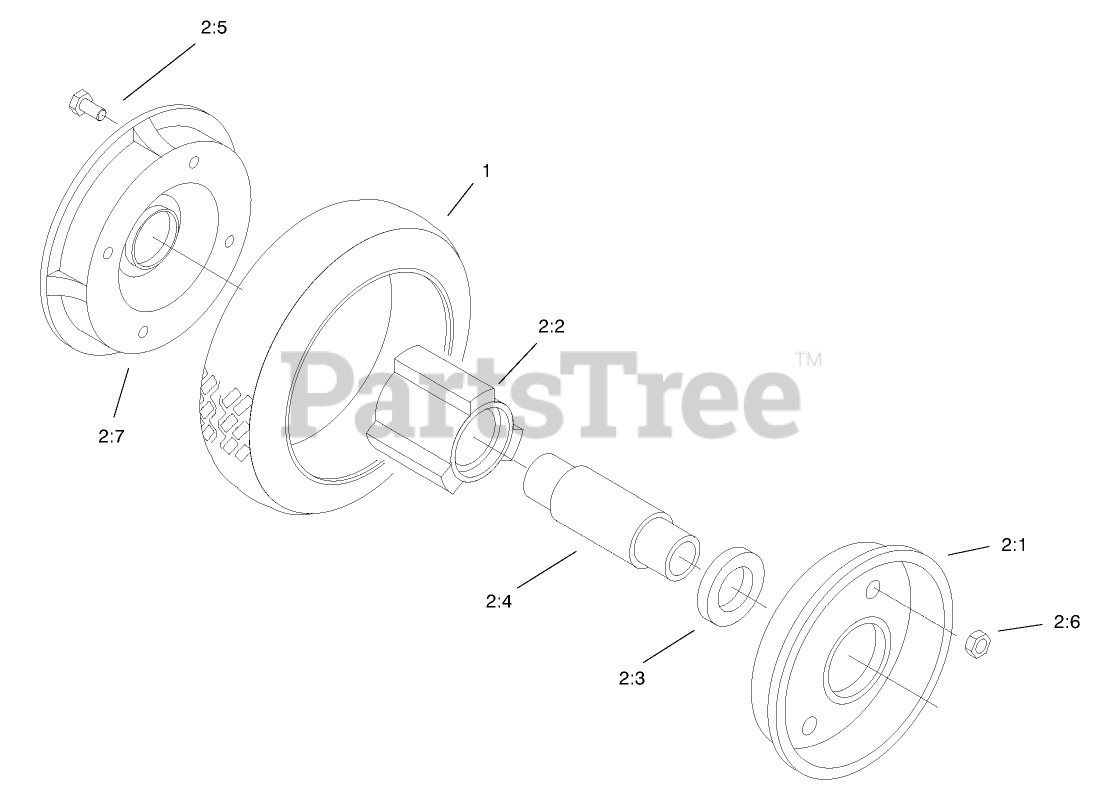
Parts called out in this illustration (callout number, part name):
2	Loose Parts Package
2:2	HUB-BEARING
2:3	BEARING-WHEEL
2:4	SPACER-BEARING
2:5	SCREW-HH
2:6	NUT-LOCK, NI
